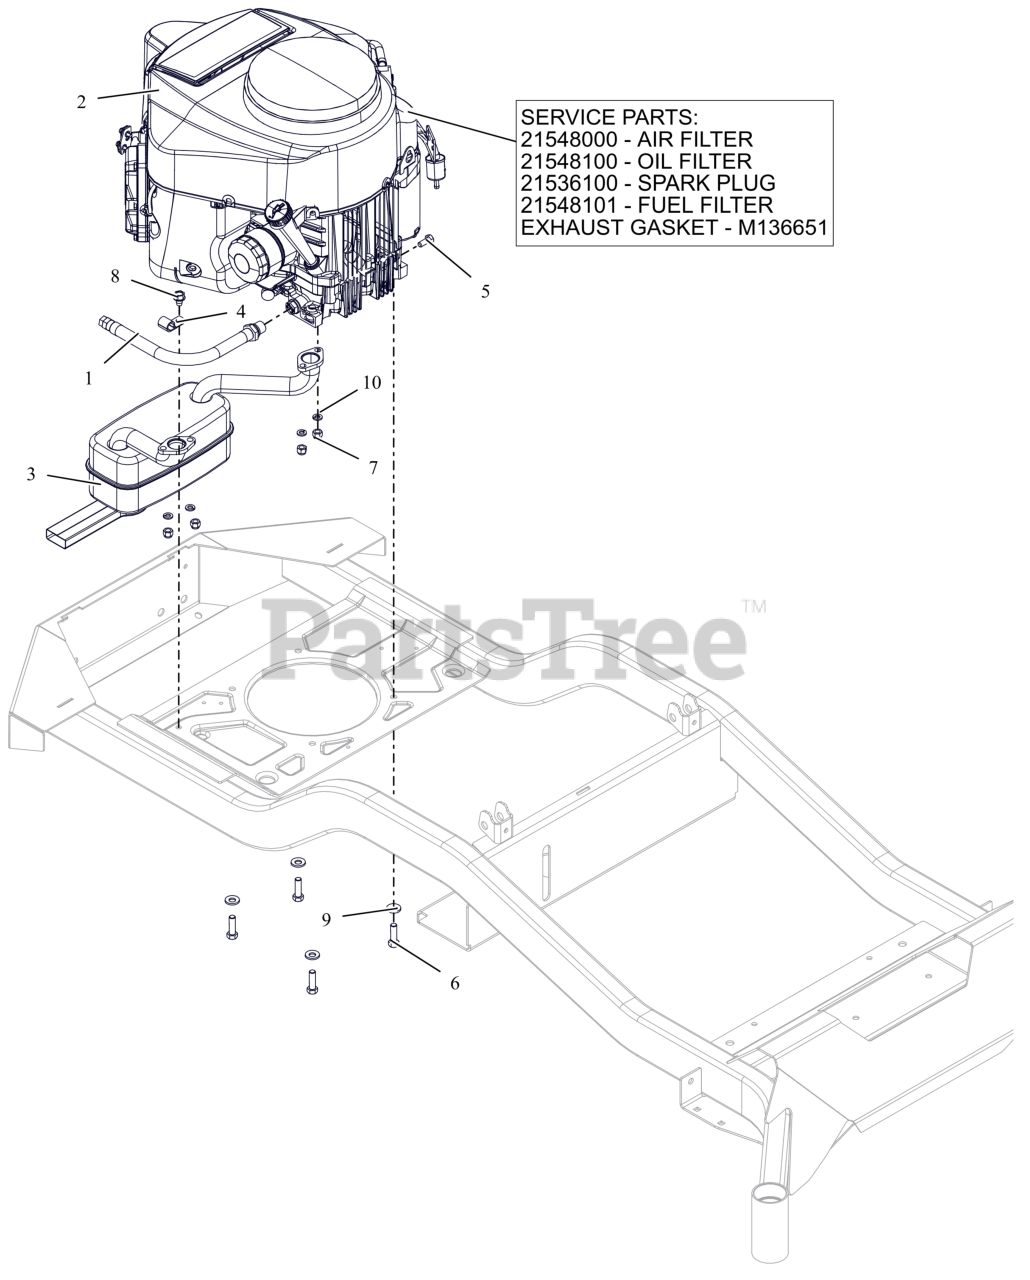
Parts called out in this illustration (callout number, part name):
1	HOSE, OIL DRAIN
2	ENGINE, KAWASAKI FR691 23HP
2	AIR FILTER, KAWASAKI FR
2	OIL FILTER, KAWASAKI FR
2	PLUG, SPARK
2	FUEL FILTER-KAWASAKI FR
2	GASKET, MUFFLER #
3	MUFFLER, KAWASAKI
4	J-CLAMP
5	BLT, HEX M8-1.25X20 G8.8 ZCC
6	BLT, HEX .38-16X1.25 G5 ZCC NT
7	NUT, LK-CTR-JAM M8-1.25 GR8.8 ZC120
8	SCR,TAP .375-16X.50 HWH TR ZCC
9	WASHER, 3/8" SPRING DISC
10	WSHR,LK-REG .312X.078 ZCC
